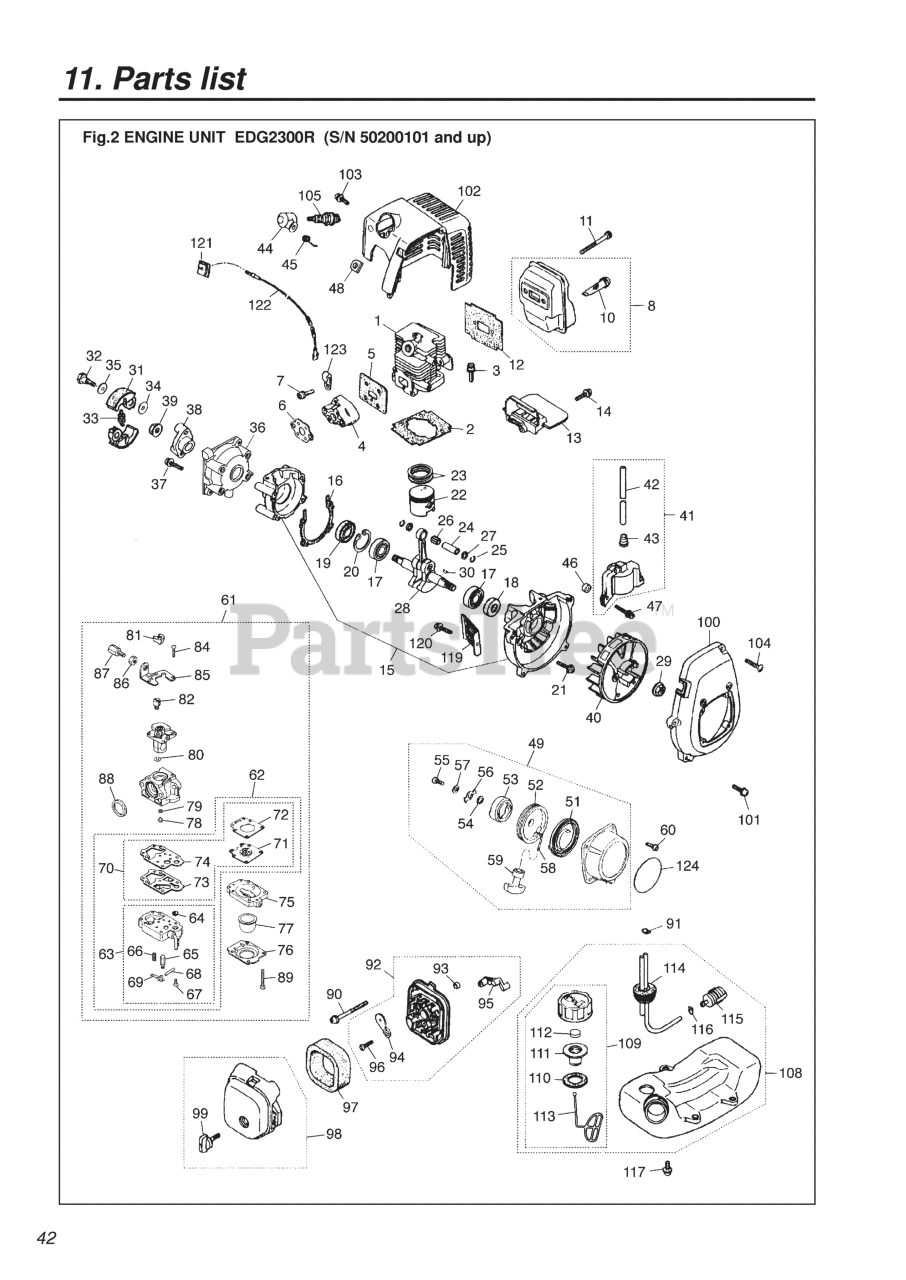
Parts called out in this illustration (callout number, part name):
1	CYLINDER
2	GASKET, BASE (RPLS -12212)
3	BOLT, M5 X 22
4	INSULATOR (REPLACES -13162)
5	GASKET (RPLS -13120)
6	GASKET (REPLACES -13130)
7	SCREW, M5X20 (RPLS.1400-75510)
8	MUFFLER ASSEMBLY
10	ARRESTER (RPLS 5850-15140)
11	BOLT, M5 x 50
12	GASKET, MUFFLER
14	SCREW, M4 X 16
15	CRANKCASE COMP.
16	GASKET (RPLS -21140)
17	BEARING
18	SEAL, OIL (RPLS 1100-21210)
19	SEAL, OIL (RPLS 1140-21220)
20	RING, SNAP, M28 x 1.2
21	BOLT, M5 X 30
22	PISTON (REPLACES 1140-41110)
23	RING, PISTON (RPLS 1850-41210)
24	PIN, PISTON 5x8x26
25	RING, SNAP (RPLS 1101-41320)
26	BEARING (RPLS 1140-41330)
27	WASHER
28	CRANKSHAFT (RPLS -42000)
30	KEY
31	SHOE (RPLS 1100-51114)
32	BOLT
33	SPRING, CLUTCH (RPLS-51220)
34	WASHER, FLAT (USE 182303)
36	CASE, CLUTCH (REPLACS -21161)
37	SCREW
38	PLATE, CLUTCH
41	COIL
43	CAP
44	CAP
45	SPRING
46	SPACER (RPLS -71260)
47	BOLT
48	GROMMET
49	RECOIL-ASSY (RPLS -75101)
51	SPRING
52	REEL (RPLS-75130 & 1861-75130)
53	RACHET (RPLS.-75140)
54	SPRING (REPLACES -75150)
56	RETAINER
57	WASHER
58	ROPE
59	KNOB (REPLACES-75180)
60	SCREW, M4 x 12
61	CARBURETOR
63	BODY, PUMP
64	SCREEN
65	VALVE
66	SPRING
67	SCREW
68	PIN
69	LEVER
71	DIAPHRAGM
72	GASKET
73	DIAPHRAGM
74	GASKET
75	BODY, PURGE
76	COVER, PUMP
77	PUMP, PRIMING
78	JET
79	RING, O
80	RING
81	WASHER
82	SWIVEL
84	SCREW
86	NUT, CABLE ADJUSTER
87	SCREW, CABLE ADJUSTER
88	RING, PACKING
89	SCREW
90	SCREW, M5 x 60
91	CLIP
92	BODY-A (RPLS -82101)
93	SLEEVE
94	PLATE, CHOKE (RPLS-82130)
95	LEVER, CHOKE
96	SCREW
97	ELEMENT
98	COVER ASSY (RPLS -82202)
99	KNOB (RPLS -82220)
100	COVER, FAN
101	SCREW, M5X20 (RPLS.1400-75510)
102	ENGINE COVER (RPLS-32100)
103	SCREW, M5 x 12
104	SCREW, HOUSING
105	PLUG (BPMR7A)(RPLS 5933-73110)
108	TANK ASSY (RPLS-85001)
109	CAP ASSY (RPLS. 5601-85201)
110	PACKING
111	HOLDER - A (RPLS 5601-85230)
112	FILTER
113	STOPPER
114	PIPE COMPLETE
115	FILTER (RPLS 1850-85300)
116	CLIP (REPLACES 2841-31280)
117	SCREW
120	SCREW,M5 X 14 (RPLS 1400-15510
122	CORD COMP
123	CLAMP (RPLS 1140-72231)
124	LABEL, RECOIL
